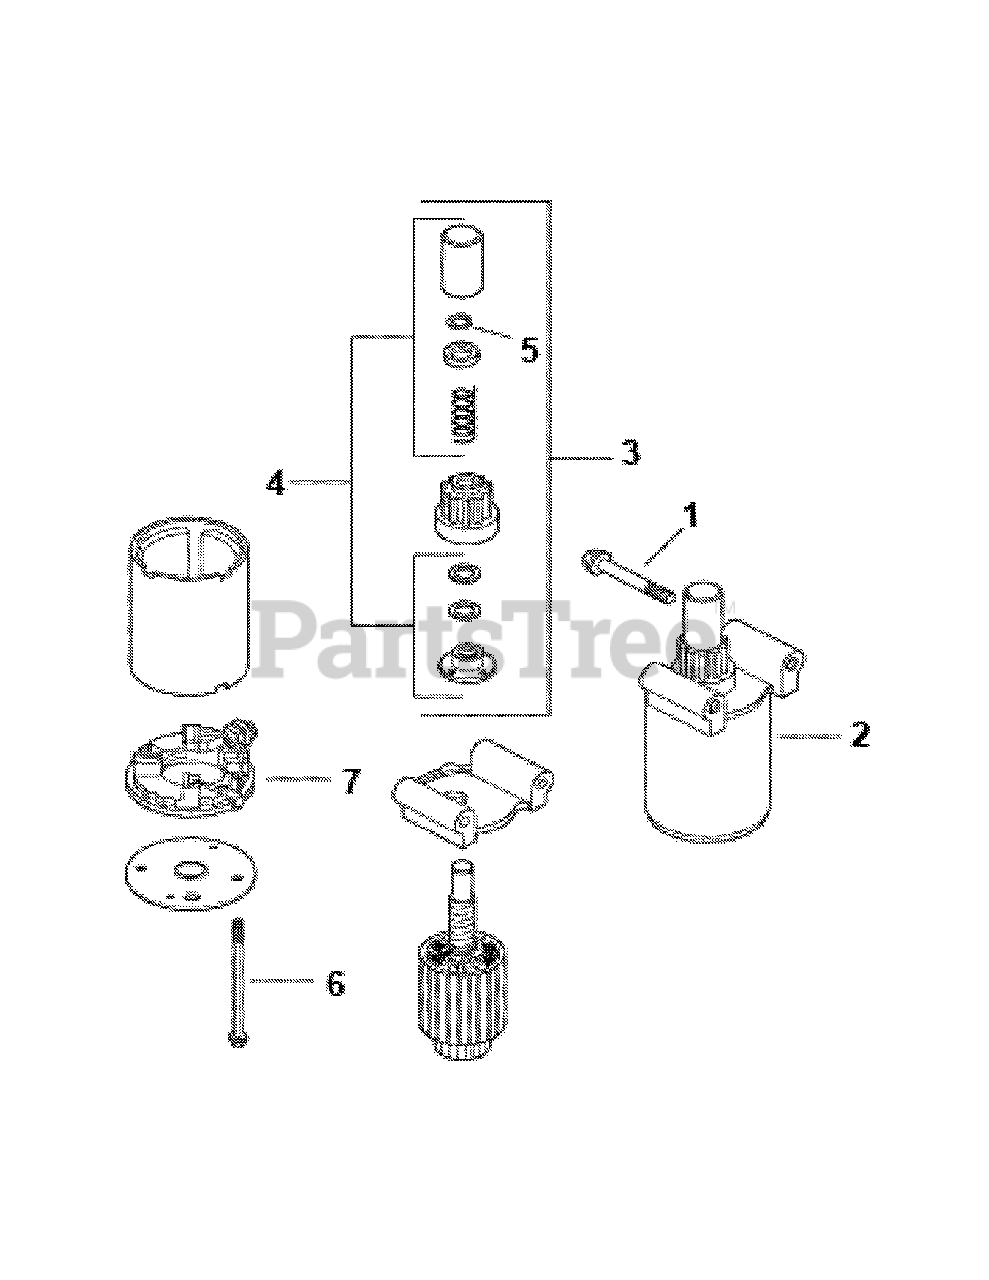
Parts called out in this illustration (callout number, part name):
1	Hex Flange Screw (M8 x 1.25 x 80)
2	Starter Assembly
4	Drive Parts kit
5	Retaining Ring
7	End Cap Commutator
